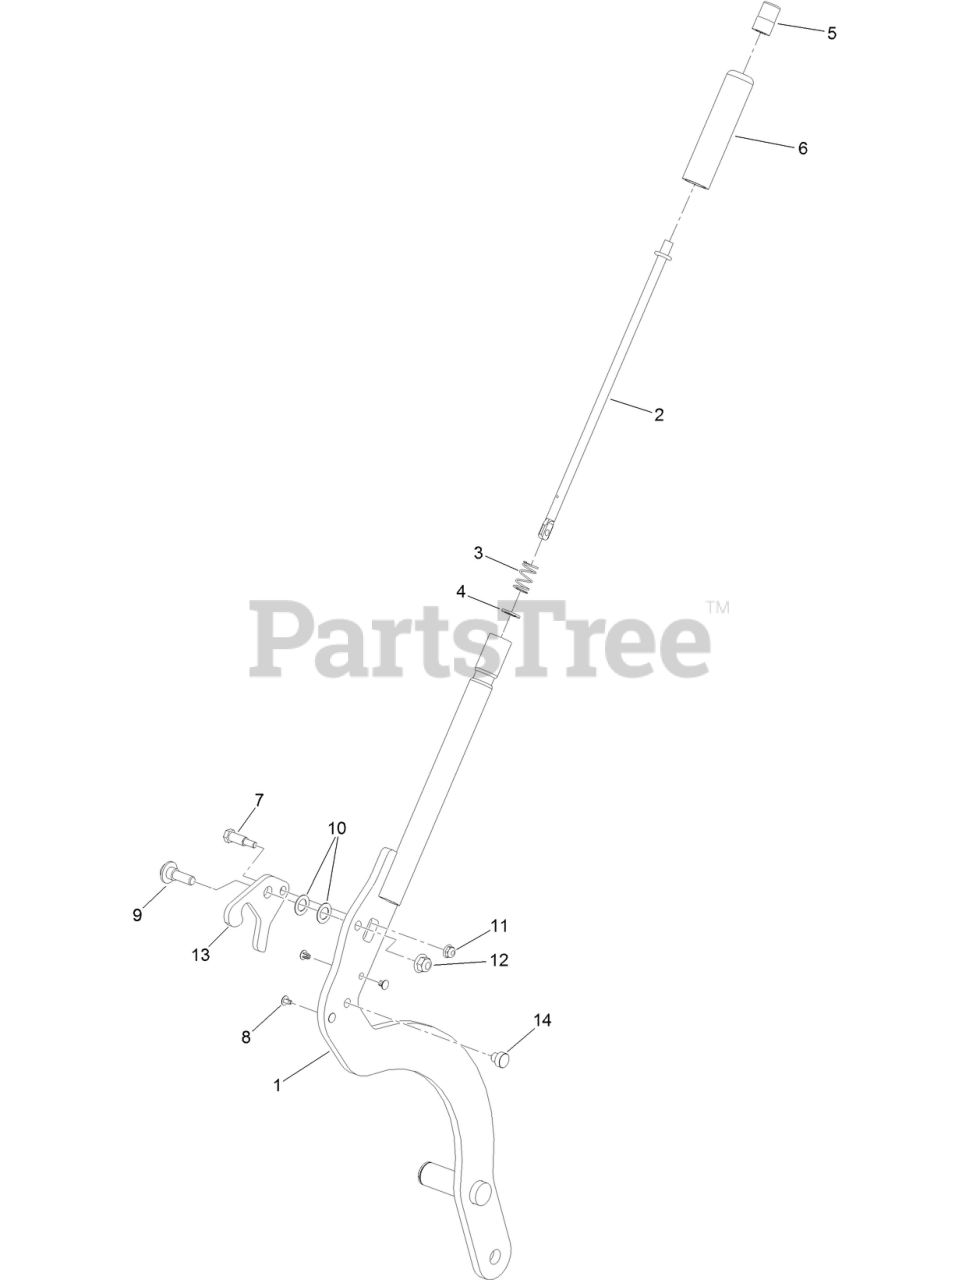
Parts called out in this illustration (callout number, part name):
1	LEVER-LIFT
2	ROD-LATCH, RELEASE
3	SPRING-COMPRESSION
4	WASHER-SPECIAL
7	BOLT-SHOULDER
9	SCREW-SHOULDER, HWH
10	WASHER
11	NUT-HF
12	NUT-HF, NI
13	LATCH-HOC
14	PLUG-WEAR
